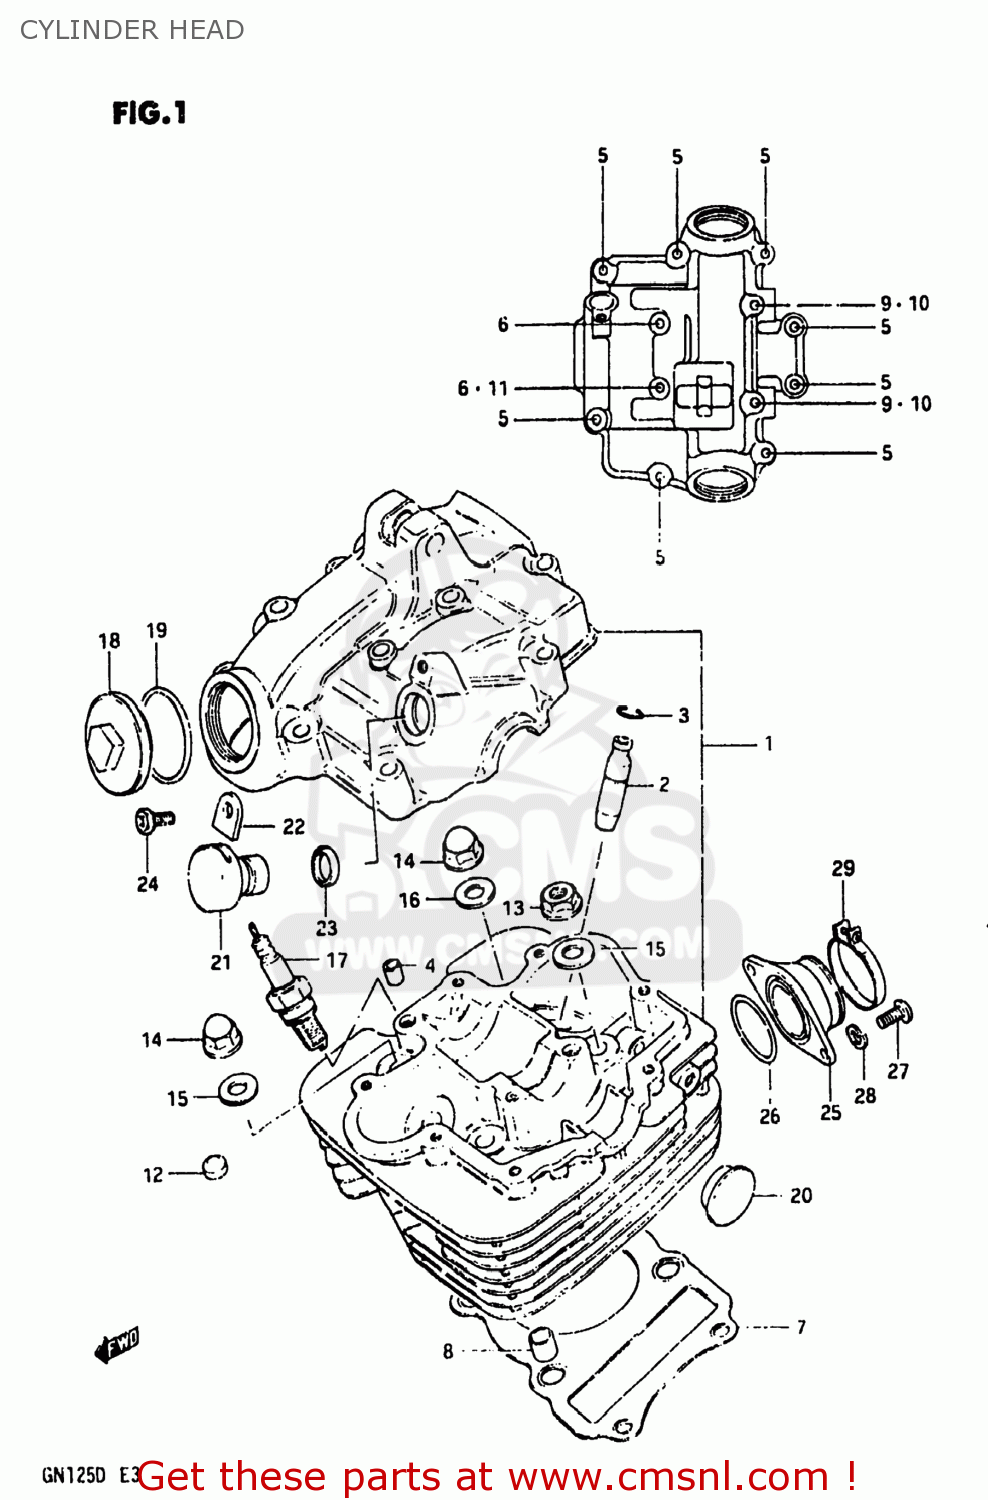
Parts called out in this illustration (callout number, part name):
1	HEAD ASSEMBLY,CYLINDER
2	GUIDE,VALVE
3	RING,SNAP
4	PIN(6.2X8X11)
5	BOLT 6X35
6	BOLT (6X60)
7	GASKET,CYLINDER HEAD
8	PIN
9	STUD 6X25
10	NUT
11	GASKET(6.2X11X1).2 (NAS)
12	PAD,CYLINDER HEAD
13	NUT
14	NUT
15	WASHER(8.5X19X2.3)
16	GASKET (NAS)
17	SPARK PLUG D8EA
18	CAP,INSPECTION
19	O RING(D:3,ID:29.5)
20	PLUG(OD:22.5)
21	PLUG,TACH GEAR SLEEVE HOLE
22	PLATE,TACH DRIVE GEAR SLEEVE
23	SEAL,TACHOMETER DRIVEN
24	SCREW(5X12)
25	PIPE,INTAKE
26	O RING(D:2.4,ID:31.7)
27	SCREW
28	LOCK WASHER
29	CLAMP
